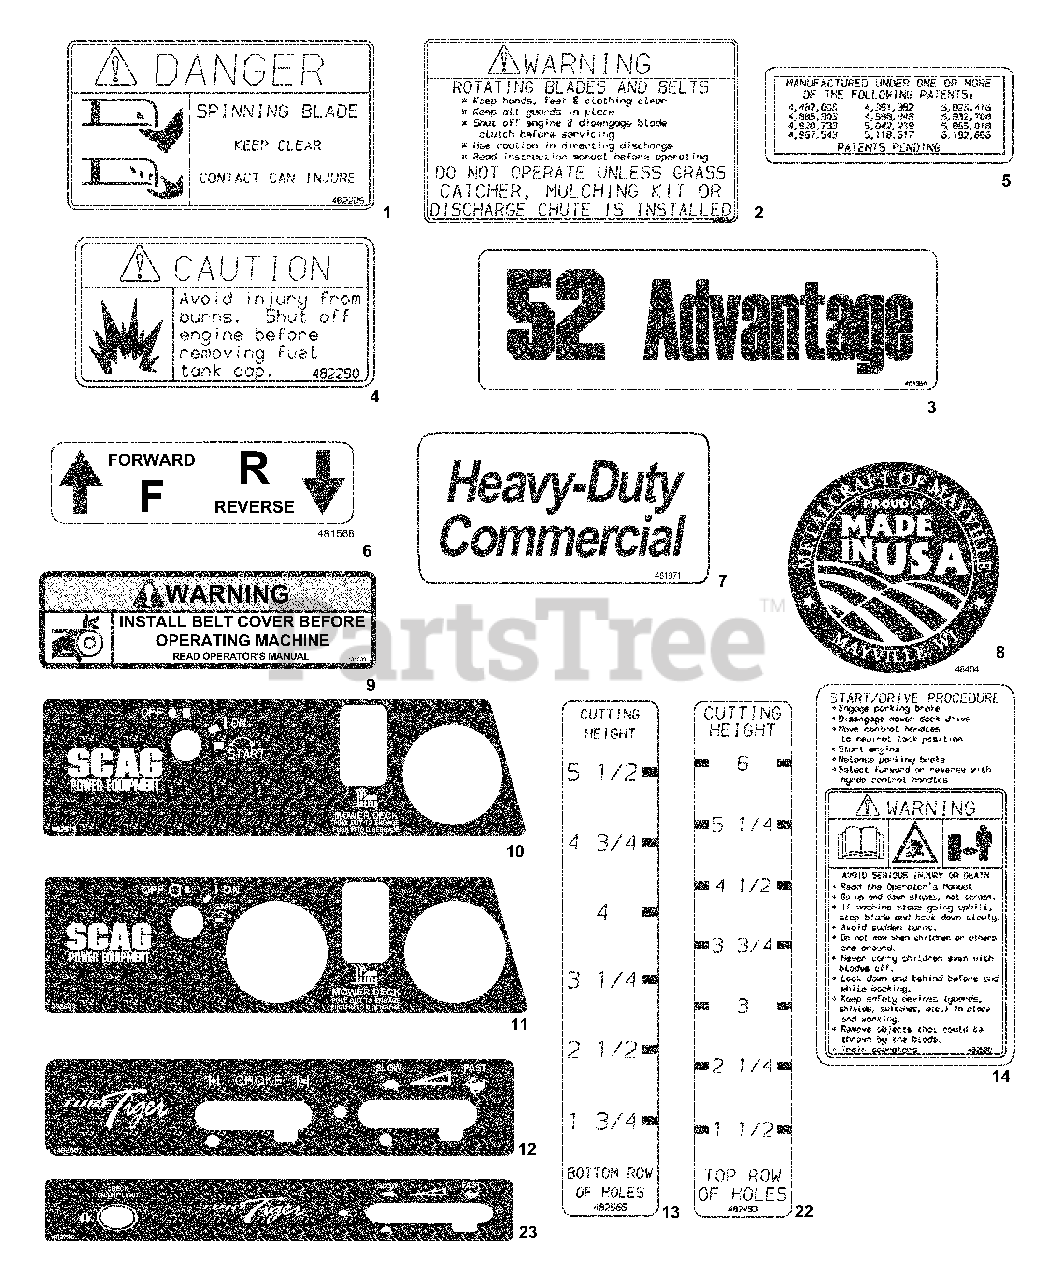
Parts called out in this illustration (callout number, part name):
1	Decal, Danger-Spinning Blades
2	Decal, Warning-Rotating Blades
3	Decal, 52 Advantage
4	Decal, Fuel Tank
5	Decal, Patents
6	Decal, Traction Control
7	Decal, Heavy Duty Commercial
8	Decal, MetalCraft-Made In USA
9	Decal, Belt Cover
10	Decal, Instrument Panel-Upper (Air Cooled)
11	Decal, Instrument Panel-Upper (Kawasaki)
12	Decal, Instrument Panel-Lower
13	Decal, Cutting Height - Lower
14	Decal, Start/Drive Procedure
22	Decal, Cutting Height - Upper
23	Decal, Instrument Panel - Lower (Kawasaki 29HP-DFI only)
